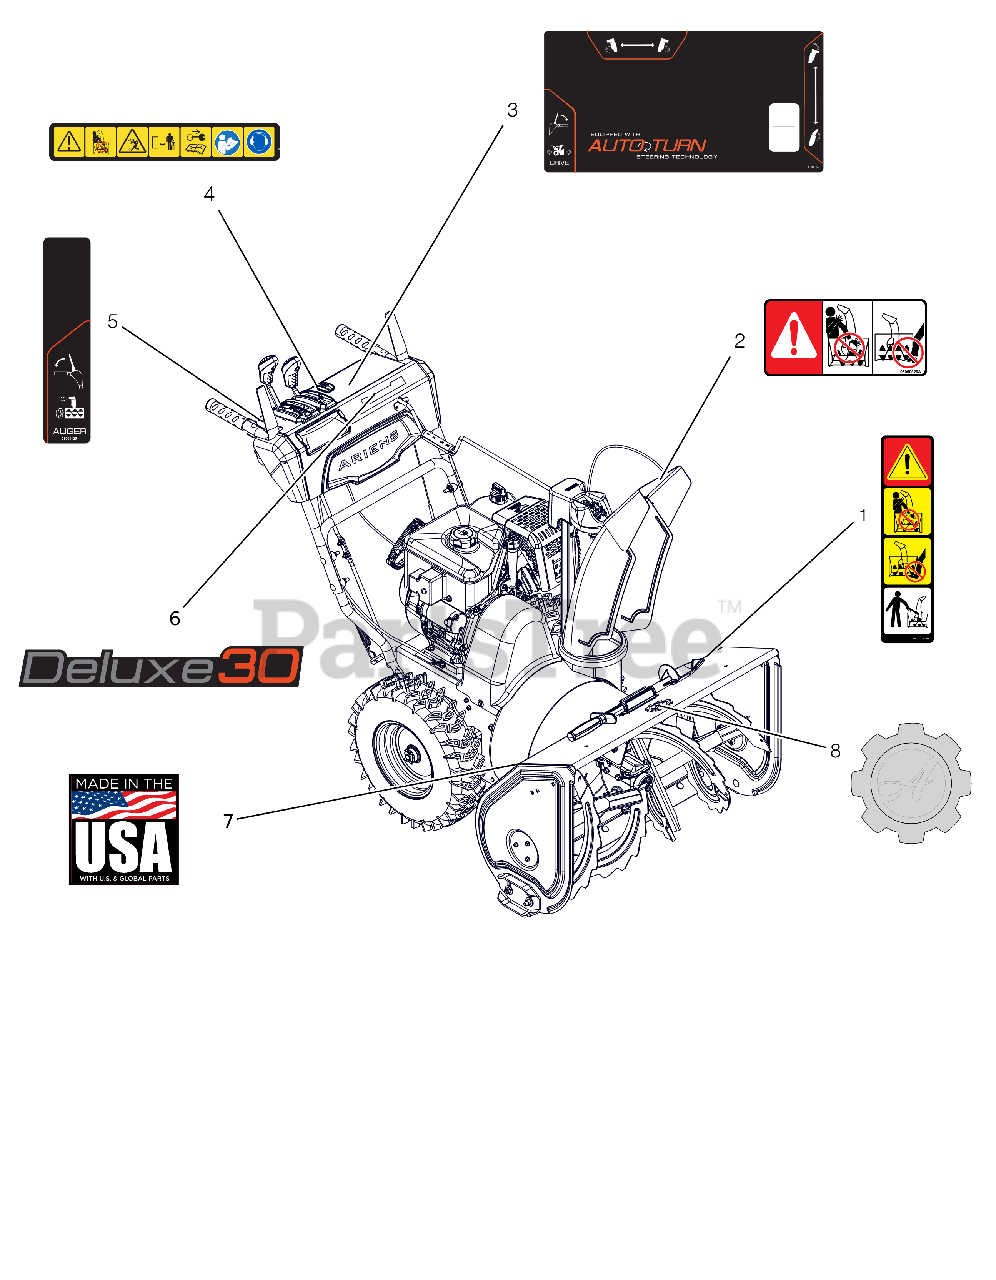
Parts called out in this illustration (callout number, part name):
1	DECAL, DANGER - ROTATING PARTS
2	DECAL, DANGER
3	DECAL,CONTROL-LG ID
4	DECAL,DASH - SAFETY
5	DECAL,CONTROL-RH CONTROL
6	DECAL, DASH - DELUXE 30
7	DECAL, MADE IN USA
8	DECAL, ARIENS-GEAR BADGE -THK
